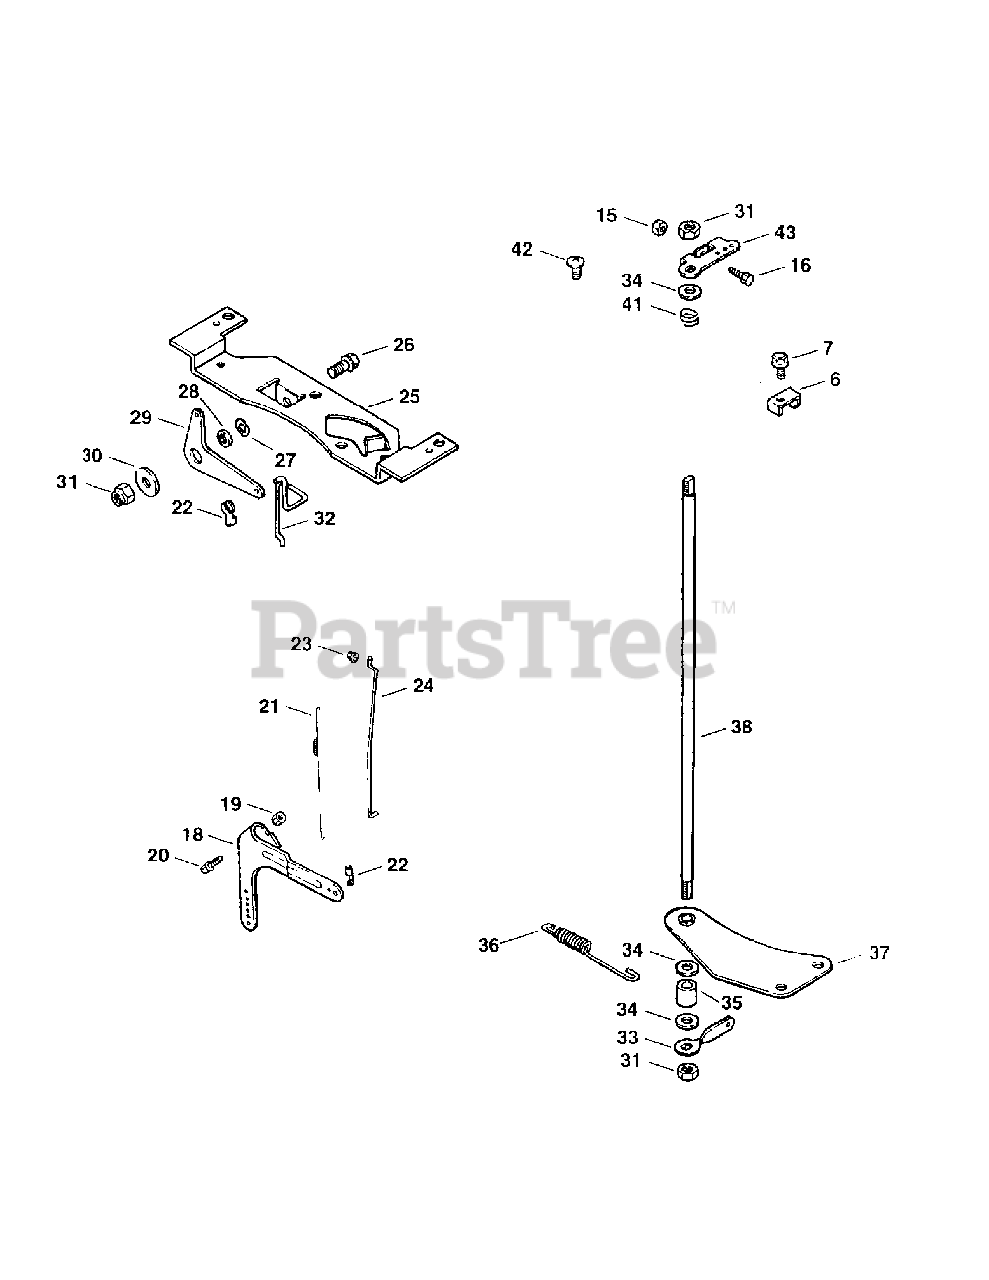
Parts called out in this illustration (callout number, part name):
6	Clamp, Cable
7	Screw, Hex Flange
15	Nut, Hex Flange
16	Screw, Hex Cap
18	Lever, Governor
19	Nut, Hex Flange
20	Screw, Hex Cap
21	Spring, Linkage
22	Bushing, Linkage (Black)
23	Bushing, Linkage (Natural)
24	Linkage, Throttle
25	Bracket, Control
26	Screw, Hex Flange
27	Washer, Spring
29	Lever, Choke
30	Washer, Plain 1/4"
31	Nut, Hex
32	Linkage, Choke
33	Lever, Throttle Control
34	Washer, Plain 1/4"
36	Spring, Governor
37	Bracket, Throttle Shaft
38	Shaft, Throttle
41	Spring, Throttle Shaft
42	Screw, Phillips Head
43	Lever, Throttle Control
